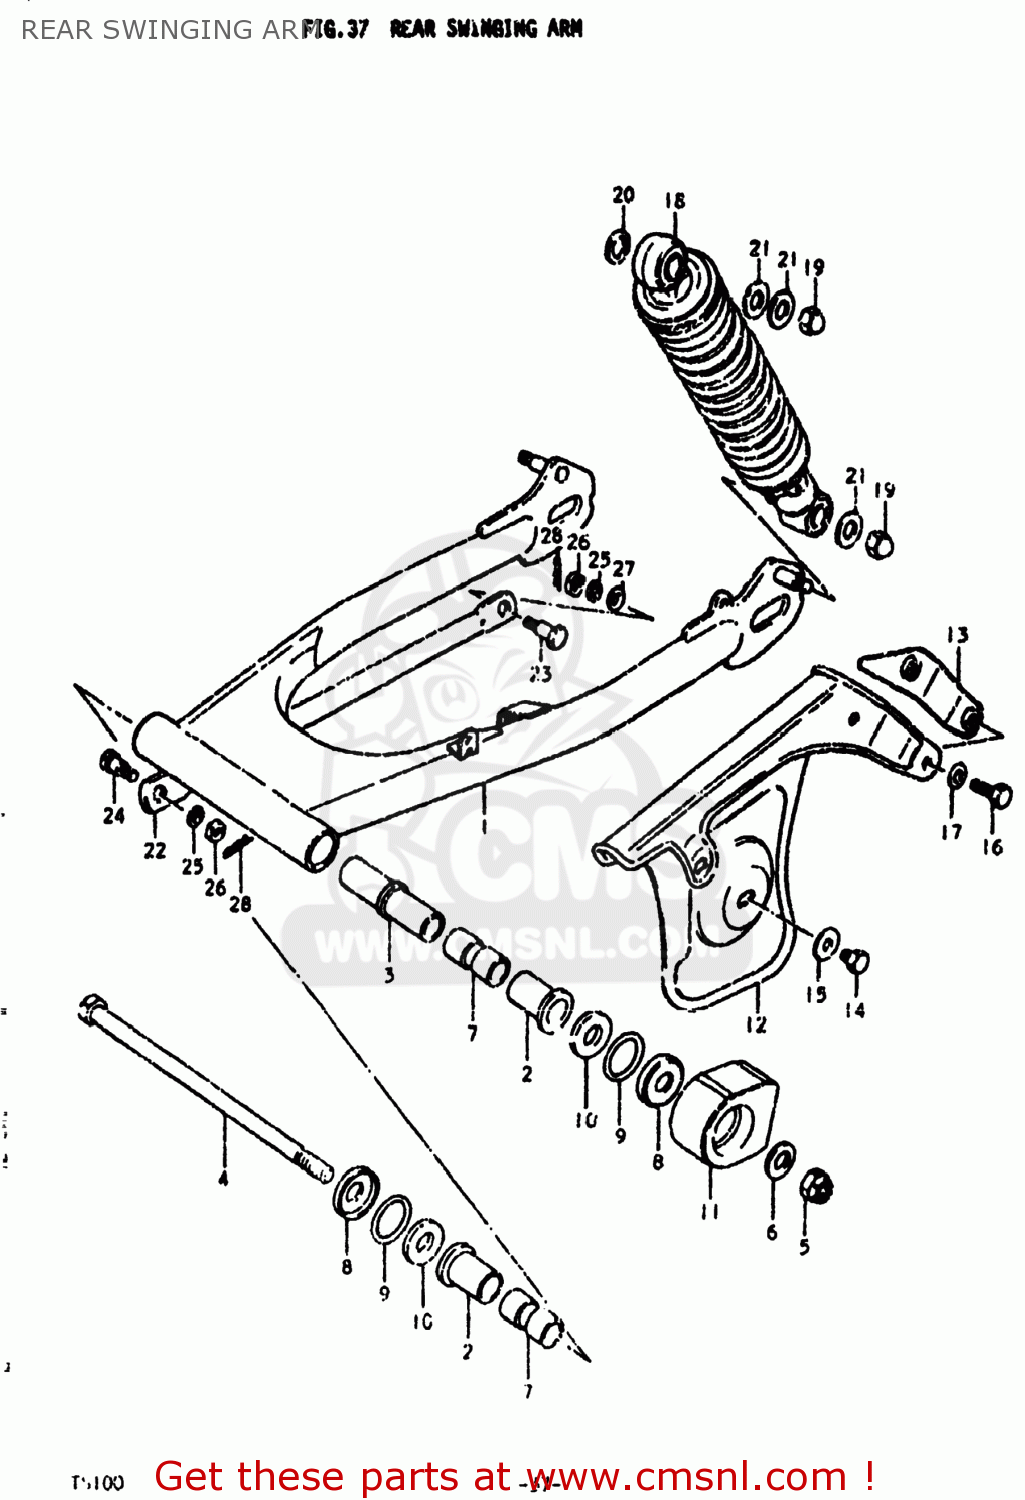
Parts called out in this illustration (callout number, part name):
1	SWING ARM ASSEMBLY,REAR
2	BUSH
3	SPACER,RR SWGARM PIVOT CTR
4	SHAFT,REAR SWING ARM
5	NUT
6	WASHER
7	SPACER,RR SWGARM PIVOT
8	COVER,SWGARM BUSH DUST SEAL
9	O RING(D:2,ID:24.5)
10	WASHER(12.5X24X2.3)
11	BUFFER,CHAIN TOUCH DEFENSE
12	CASE,CHAIN
13	REINFORCEMENT,CHAIN CASE
14	BOLT(6X8)
15	WASHER
16	BOLT, UPPER
17	WASHER
18	ABSORBER ASSEMBLY,REAR SHOCK
19	NUT, LOWER LH
20	WASHER
21	WASHER
22	TORQUE LINK,REAR
23	BOLT(8X22)
24	BOLT(8X26.5)
25	LOCK WASHER
26	NUT
27	WASHER
